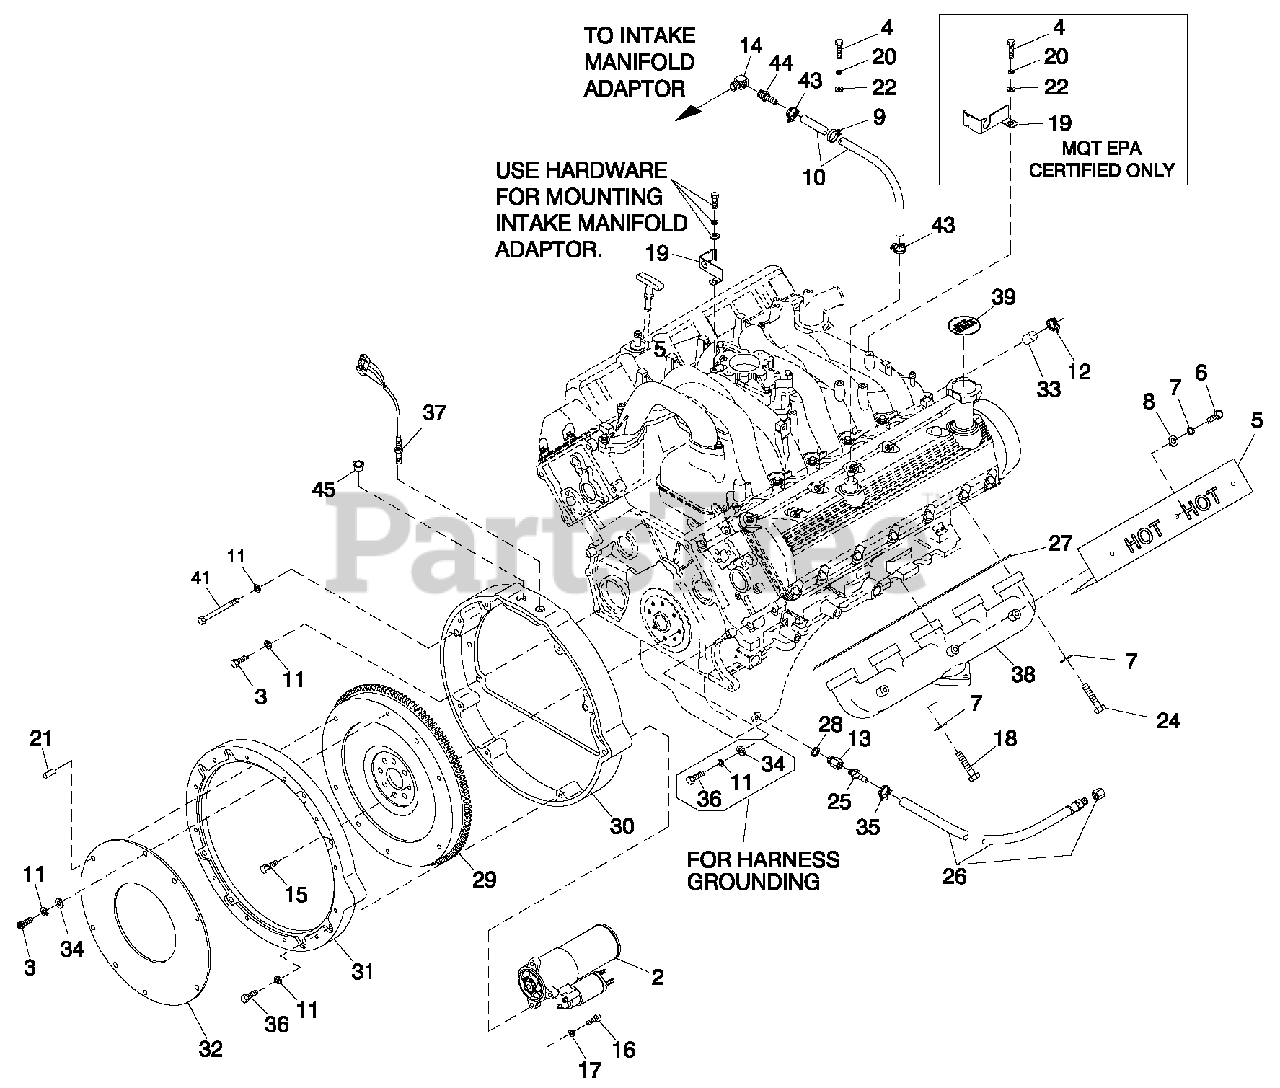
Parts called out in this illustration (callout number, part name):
2	STARTER MOTOR FORD V-10 ENGINE
3	SCREW SHC M10-1.5 X 35 G12.9
4	SCREW HHC M6-1.0X 16 G8.8
5	HEAT SHIELD EXHAUST
6	SCREW HHC 5/16-18 X 1/2 SSTL
7	WASHER LOCK M8 SSTL
8	WASHER FLAT M8 SS
9	CLAMP VINYL .75X.343Z
10	HOSE COOL 5/8" ID 250#WP (14")
11	WASHER LOCK M10
12	CLAMP HOSE #10 .56 - 1.06 (2300 & 3000RPM UNITS ONLY)
13	ADAPTER M14-1.50X 3/8 NPT
14	ELBOW 90D1/4 NPT F-M BRASS
15	SCREW HHC M10-1.0 X 25 G10.9
16	SCREW SHC M8-1.25 X 30 G12.9
17	WASHER LOCK M8-5/16
18	SCREW HHC M8-1.25 X 35 SS F-TH
19	BRACKET SIGNAL CONDITIONER
20	WASHER LOCK M6-1/4
21	DOWEL PINM10X24
22	WASHER FLAT 1/4 ZINC
24	SCREW SHC M8-1.25X 35 SS
25	BARBED STR 3/8 NPT X 3/8
26	HOSE DRAIN ASSY 28"
27	GASKET EXHAUST MANIFOLD
28	WASHER NYLON .565
29	ASSEMBLY 6.8L G-BOX FLYWHEEL
30	FLYWHEEL HOUSING MACH 6.8L V10
31	COVER FLYWHEEL MACH 6.8L V-10
32	PLATE DAMPNER RETNR
33	CAP HOSE (2300 & 3000RPM UNITS ONLY)
34	WASHER FLAT 3/8-M10 ZINC
35	CLAMP HOSE .38-.87
36	SCREW SHC M10-1.5 X 25 G12.9
37	ASSY MAGPICKUP(3/8-24 MALE)
38	EXH MANIFOLD MACH 6.8L V-10
39	DECAL REFER TO OWNERS MANUAL
41	SCREW SHC M10-1.50 X 100 G10.9
43	CLAMP HOSE #10 .56-1.06
44	BARBED STR 1/4 NPT X 5/8
45	PLUG PLASTIC 3/8 NPT
